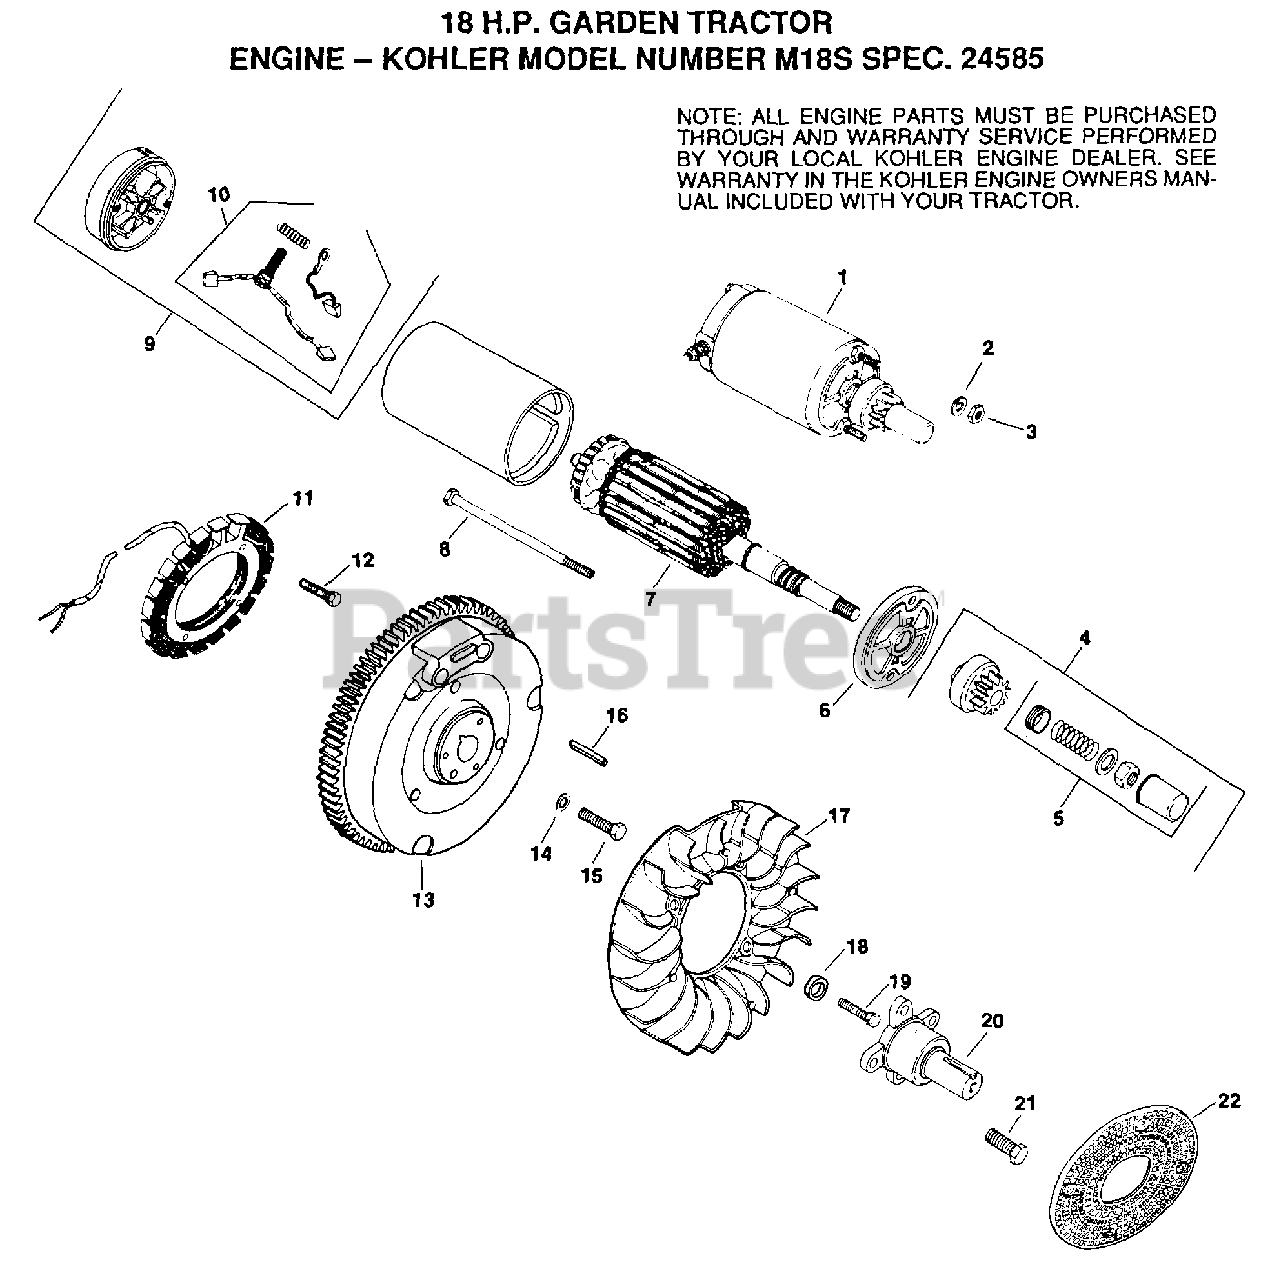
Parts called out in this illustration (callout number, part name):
5	KIT, DRIVE PARTS
6	CAP, DRIVE END
9	CAP, COMMUTATOR END
15	SCREW, 3/8-24X1-1/4
19	SCREW, HEX 1/4-20 X 5/8
20	SHAFT, FRONT DRIVE
22	SCREEN, GRASS
